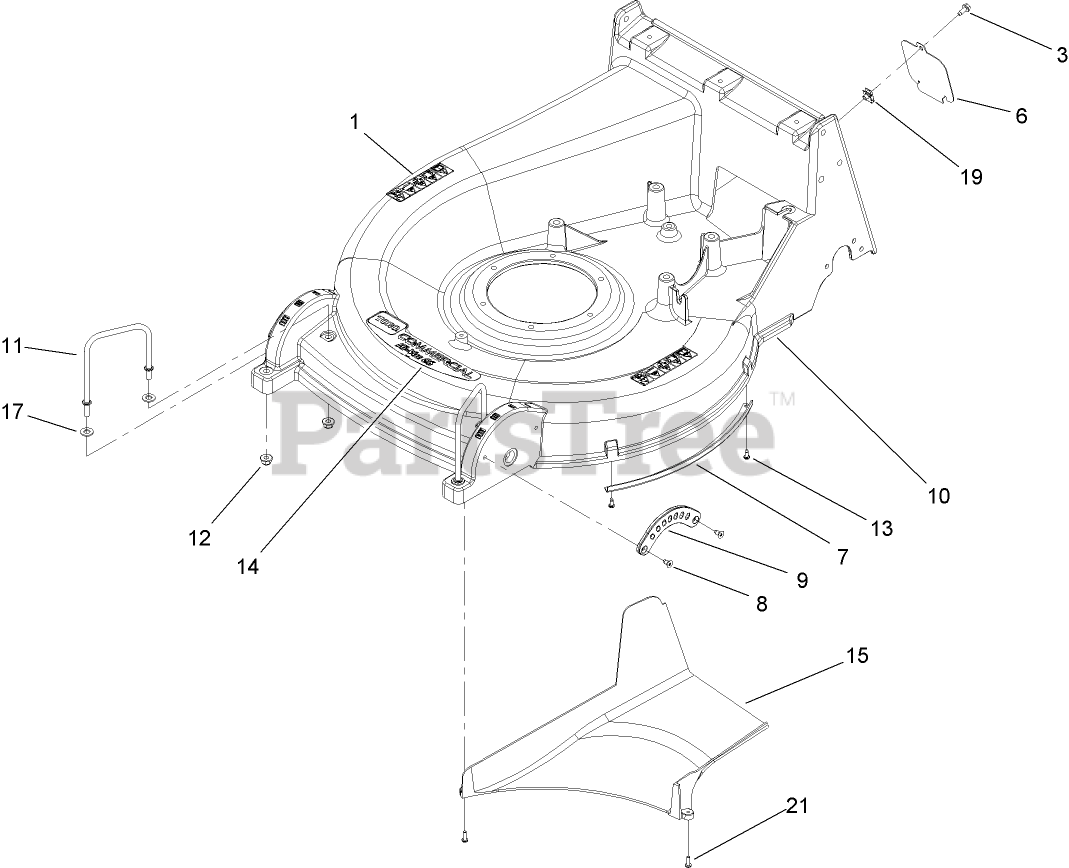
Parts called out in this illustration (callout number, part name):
1	DECAL-DANGER
3	SCREW-HWH
7	GUARD-EDGE
9	QUADRANT-FRONT
10	DECK
11	HANDLE-DECK
12	NUT-HF, NI
13	SCREW-FORMING, THREAD
15	CHUTE-PLASTIC
17	WASHER-FLAT
21	SCREW-PPHTF
